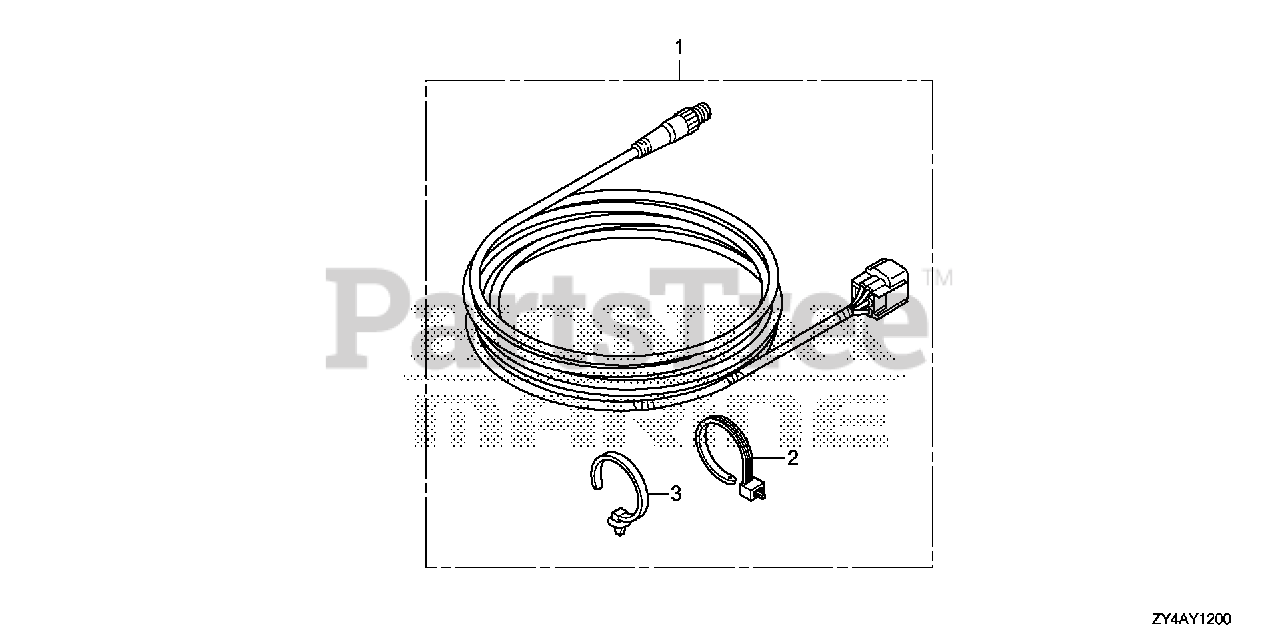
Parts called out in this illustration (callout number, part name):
1	KIT, CABLE (6FT) (NMEA)
2	TIE, CABLE
3	CLIP, HARNESS BAND (155.3MM) (BLACK)
